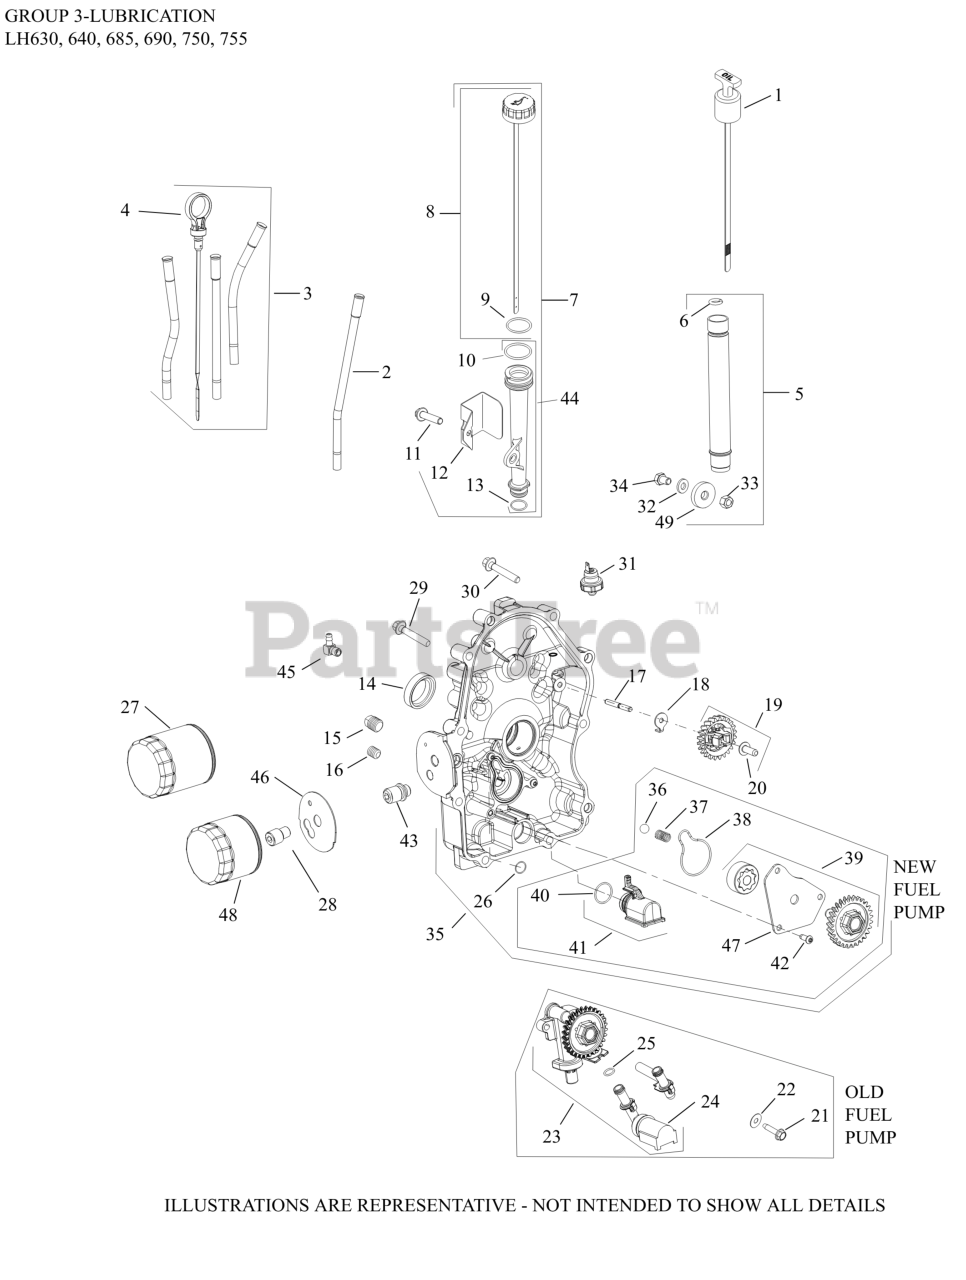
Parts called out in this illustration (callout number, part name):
3	KIT, DIPSTICK/DIPSTICK TUBES
16	PLUG, CTSK PIPE 1/8"
17	SHAFT, GOVERNOR GEAR
18	TAB, LOCKING
19	KIT, GOVERNOR GEAR W/PIN
20	PIN, GOVERNOR REGULATING
21	SCREW,FLG THD FRM M6X1.0X25-(#25086395S)
22	WASHER, FLAT 6 MM
23	PUMP ASSEMBLY, OIL-USE 24 393 53-S
24	PICK-UP, OIL
25	O-RING, OIL PICK-UP
27	OIL FILTER
28	NIPPLE, OIL FILTER-(#2413609S)
29	SCREW, FLG M8X1.25X45
31	SENSOR, OIL PSI
35	CLOSURE PLATE ASSY-USE 24 009 211-S
